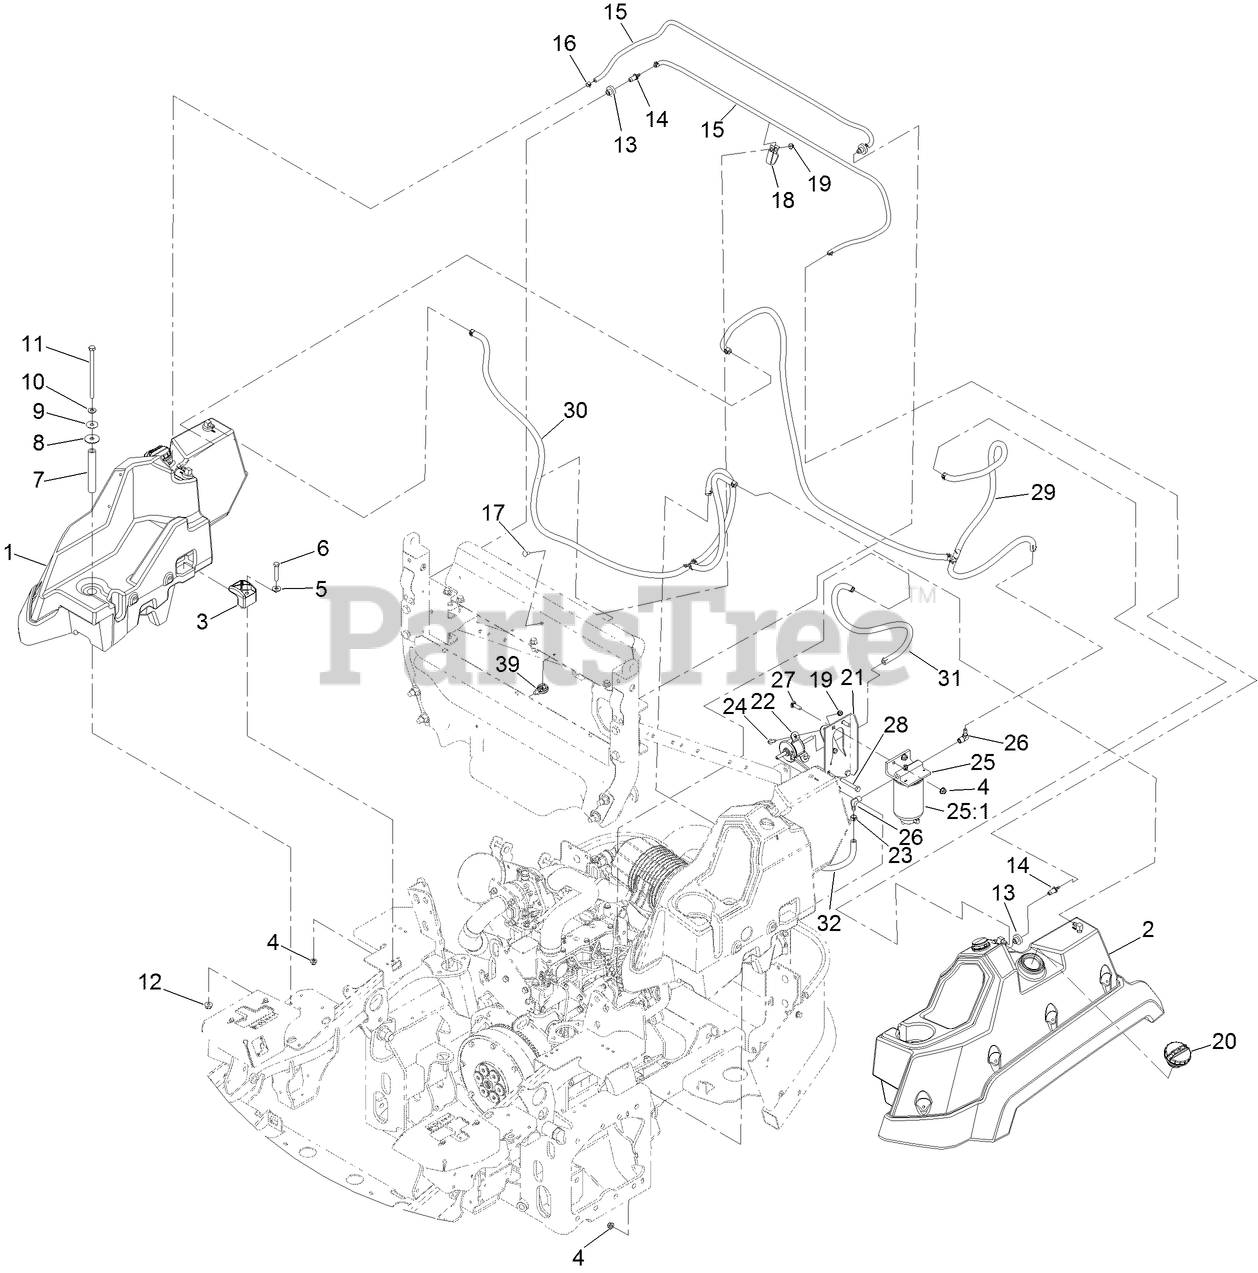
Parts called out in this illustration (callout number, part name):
1	RH FUEL TANK ASM
2	LH FUEL TANK ASM
4	NUT-HF, NI
5	WASHER-FLAT
6	SCREW-HH
7	TUBE-SPACER
8	WASHER-RUBBER
9	WASHER-PLAIN
10	WASHER-FLAT
11	SCREW-HH
12	NUT-HF, NI
13	BUSHING
14	FITTING-ORIFICE, STRAIGHT
15	HOSE-VENT, TANK
16	CLAMP-HOSE
17	SCREW-CARR
18	CLAMP-HOSE
19	NUT-HF
20	CAP-FUEL, DIESEL
21	BRACKET-FILTER AND PUMP, FUEL
22	PUMP-FUEL, ELECTRIC
23	CLAMP-HOSE
24	SCREW-HWH
25	SEPARATOR-FILTER
25:1	FILTER-SPIN ON
26	FITTING-HYD, 90
27	SCREW-CARR
28	SCREW-HH
29	LINE-FUEL, SUCTION
30	LINE-FUEL, RETURN
31	HOSE-FUEL
32	HOSE-FUEL
39	CLIP-TIE
